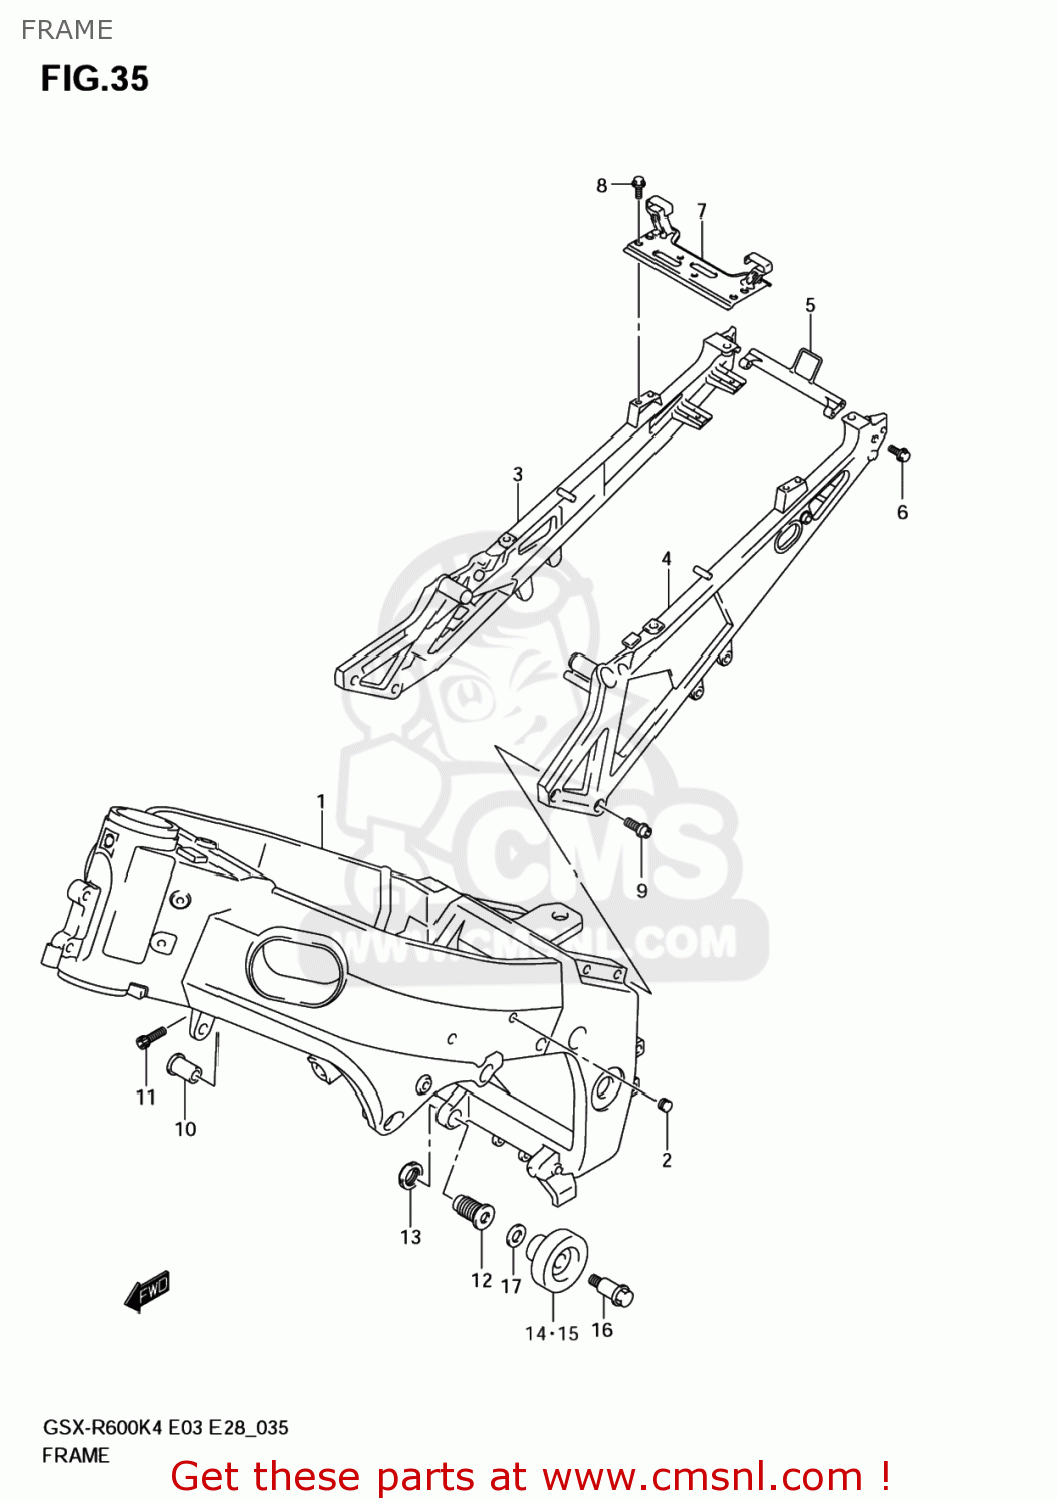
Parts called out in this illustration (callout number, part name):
1	FRAME(BLACK)
2	CAP,TANK RAIL
3	RAIL,SEAT,R
4	RAIL,SEAT,L
5	HOOK,PILLION SEAT
6	BOLT(8X25)
7	BRIDGE,SEAT RAIL
8	BOLT 6X12
9	BOLT,SEAT RAIL
10	SPACER,ENGINE MOUNTING
11	BOLT(8X32)
12	BOLT,CRANK CASE ADJUST
13	NUT,ADJUST BOLT
14	GUARD,FRAME,R
15	GUARD,FRAME,L
16	BOLT(8X35.5)
17	WASHER (8.5X16X2.6)
